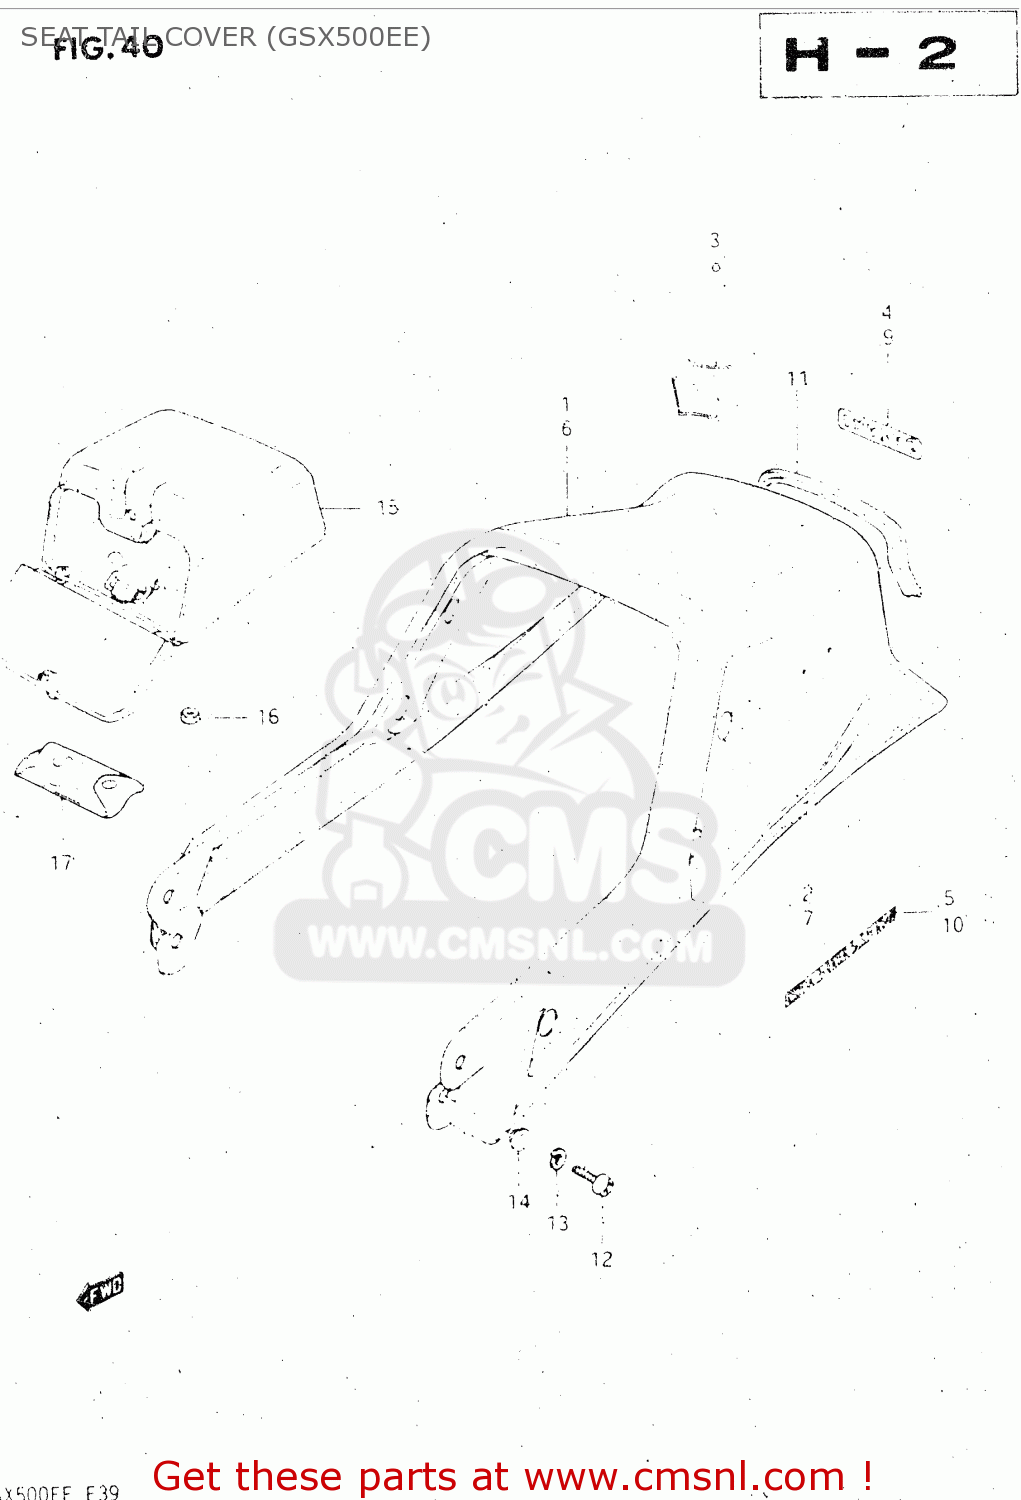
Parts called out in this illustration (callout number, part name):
1	TAIL COVER, SEAT (BLACK)
2	TAPE SET, SEAT TAIL COVER
3	EMBLEM, "S" MARK
4	EMBLEM (GOLD)
5	EMBLEM
6	TAIL COVER, SEAT (RED)
7	TAPE SET, SEAT TAIL COVER
8	EMBLEM,SEAT TAIL (S)
9	EMBLEM(WHITE)
10	EMBLEM
11	BLIND,SEAT TAIL COVER
12	SCREW
13	LOCK WASHER
14	WASHER
15	BOX,SEAT TAIL
16	NUT
17	TOOL ASSY
